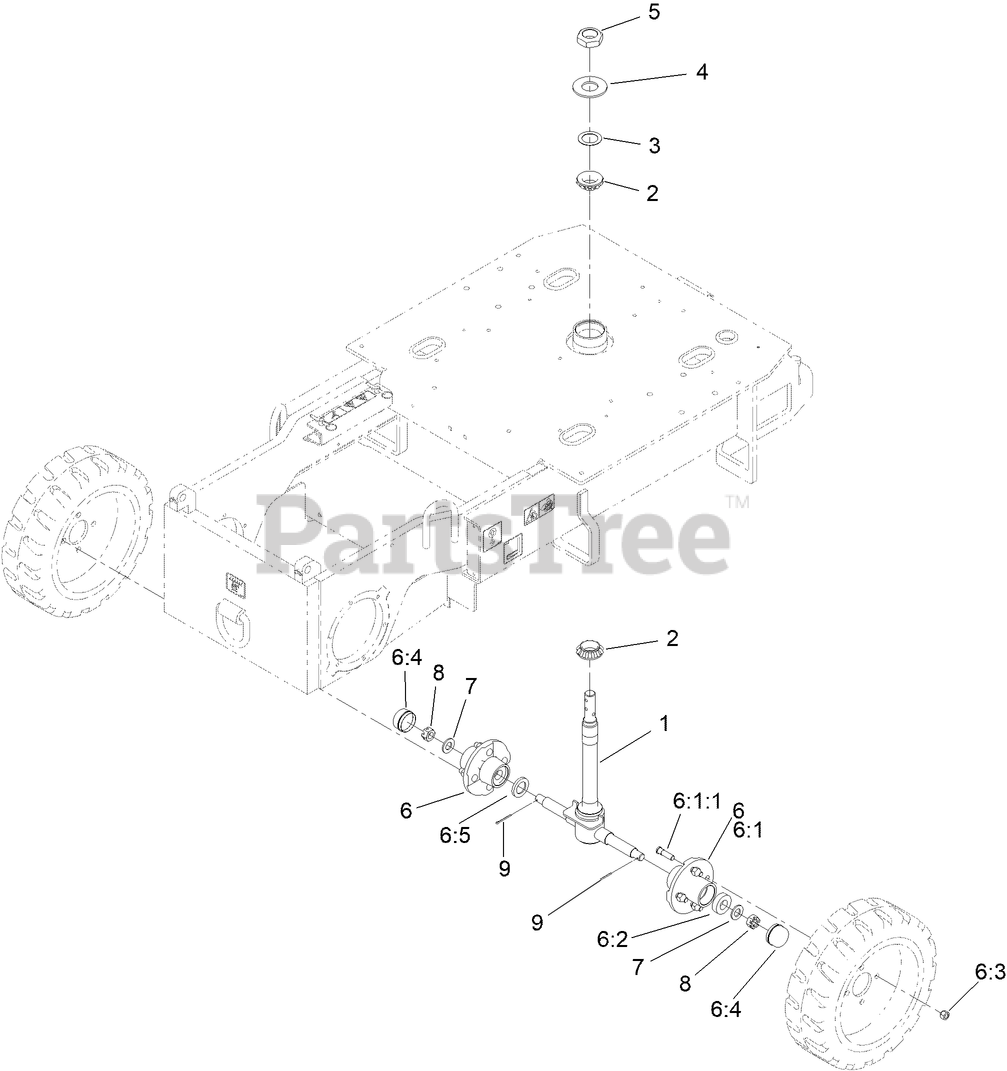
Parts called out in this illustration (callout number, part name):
1	AXLE-STEERING [PRIMED]
2	BEARING-ROLLER
3	WASHER-THRUST
4	PLATE-COVER, BEARING
6	HUB ASM
6:1	HUB-4IN
6:1:1	STUD-WHEEL
6:2	BEARING-ROLLER
6:3	NUT-LUG
6:4	CAP-DUST
6:5	SEAL-HUB, WHEEL
7	WASHER-FLAT
9	PIN-COTTER
